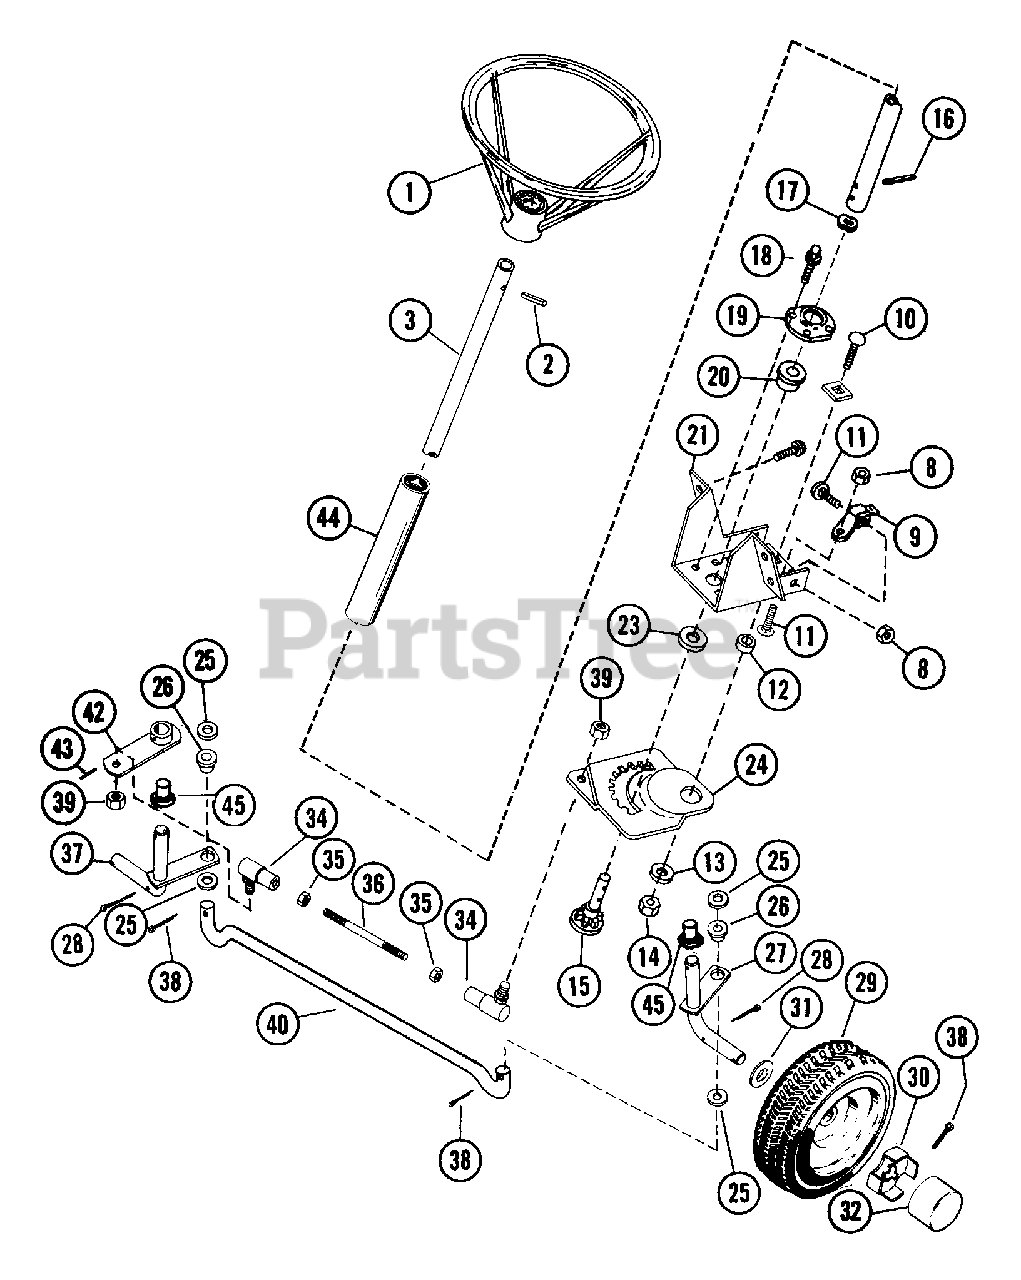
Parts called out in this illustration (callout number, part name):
1	STEERING WHEEL
2	PIN-ROLL .250X1.75
3	STEERING SHAFT
8	NUT-LK-CTR .250-20 PL
9	ADJUSTMENT BRACKET
10	BLT-RDHDSQSHNK .38-16X1.00 PL
11	BLT-RDHDSQNK .25-20X.62 PL
12	SPACER .380X.750X.236
13	WSHR-FL-STL .390X1.500X.125
14	NUT-LK-JAM-CTR .375-16 PL
15	PINION
16	PIN-ROLL .188X1.00
17	WAVE WASHER .531X.781X.125FH
18	SCR-TAP 10-24X.25 CRSLPH PL 1A
19	RETAINING PLATE
20	BSHG-FLG .625X1.156X.375 SI
21	STEERING BRACKET
22	BLT-SERHFWH .25-20X.50 PL
23	WSHR-FL-STL .630X1.250X.062 PL
24	STEERING GEAR
25	WSHR-FL-STL .505X.875X.024 PL
26	BSHG-FLG.500X.625X.312X.750NY
27	L H WHEEL SPINDLE
28	PIN-COTR .12 X 1.25 PL
29	FRONT WHEEL ASSEMBLY
29	TIRE 4.10/3.50-4
29	WHL
29	ZERK FITTING
29	BSHG-FLG .750X1.380X.750X1.557
30	SPINDLE CUP
31	SPINDLE WASHER
32	HUB CAP
34	BALL JOINT
35	NUT .375-24 PL
36	STEERING LINK
37	SPINDLE
38	PIN-COTR .12X1.0 PL
39	NUT-LK .375-24 PL
40	TIE ROD
43	PIN-GRV .250X1.25 TP A
45	FLANGE BUSHING
